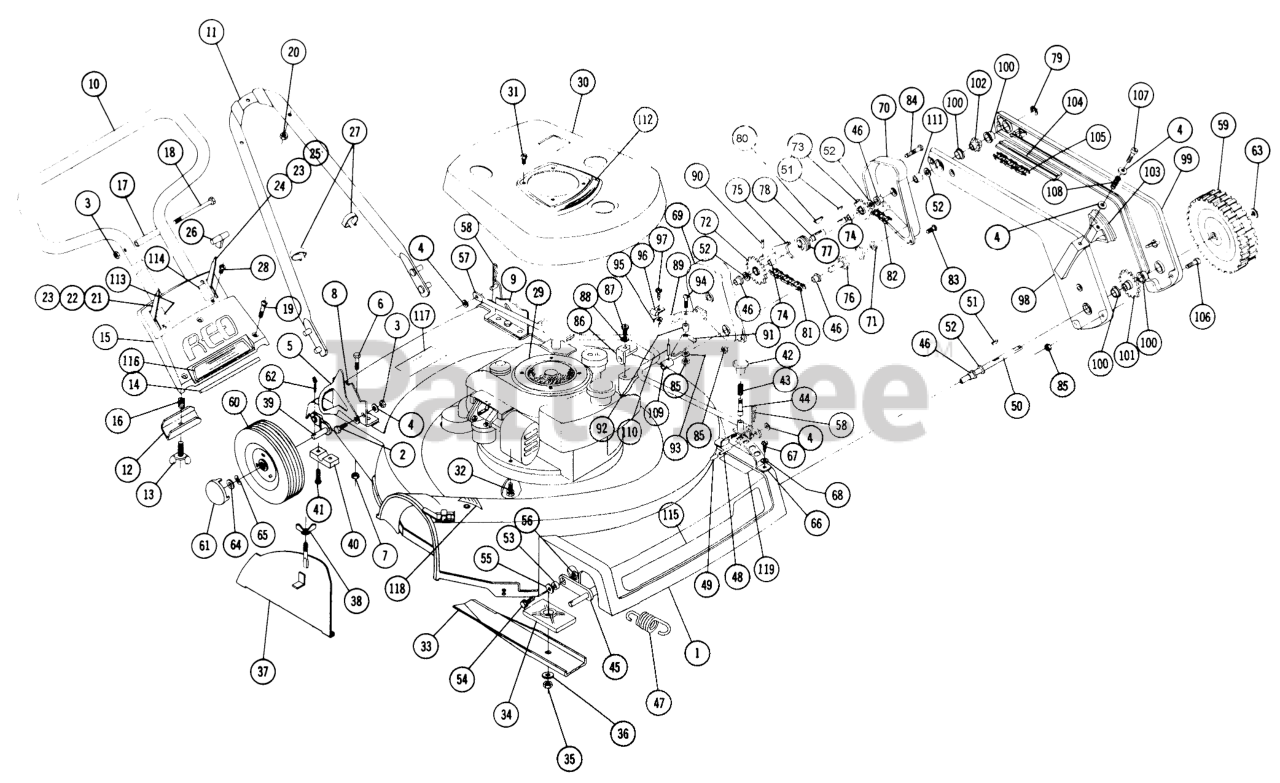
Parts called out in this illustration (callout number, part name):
1	Ass-y Deck
2	Bolt-1/4-20 x 5/8
3	Nut-Nylok
4	Washer
5	Latch-Handle Mounting
6	Bolt 5/16-18 x
7	Nut-Nylok
8	Bracket Handle R.H.
9	Bracket Handle L.H.
10	Handle-Upper
11	Handle-Lower
12	Channel-Clamp
13	Thumb Screw
14	Pin-Handle Pivot
15	Panel-Handle
16	SPRING-COMPRESSION
17	20210 '60&UP 21 SP
18	Bolt Hex 1/4-20 x 4 1/2
19	Screw Oval Head 1/4-20 x 1 1/2
20	Nut Hex 5/4-20 Nylok
21	Ass-y Throttle Control
22	31100 '60&UP 17 SNW
23	Ass-y. Cable
24	Ass-y. Clutch Control
25	Ass-y. Lever
26	Knob
27	Clip-Control
28	Screw #2 Phillips Sems #8-32 x 1/4
29	Engine
30	Shroud-Engine
31	Screw Sems 1/4-28 x 3/8
32	Screw Hex 5/16-18 x 1
33	Blade
34	Drive Blade
35	Nut Hex 5/8-18 Thin
36	Washer, 5/8
37	Ass-y Leaf Mulcher
38	Nut Wing 1/4-20
39	Ass-y Axle-Rear
40	Cap-Rear Axle Support
41	Screw Hex 1/4-20 x 7/8 Self Tap
42	KNOB
43	Spring
44	PLUNGER
45	Ass-y Height Adjustment Lever
46	BRONZE BUSHING
47	Spring
48	Roll Pin 1/8 Dia. x 1 1/2
49	Cap
50	Axle-Front
51	WOODRUFF KEY
52	Washer-Thrust
53	Spacer
54	Bolt 5/16-18 x 11/4
55	Washer
56	Nut 5/16-18
57	Rod-Wheel Adjustment Link
58	Hairpin
59	Wheel & Tire Assembly
60	Wheel & Tire Assembly
61	Cap-Hub
62	Hairpin
63	Washer
64	Washer
65	Washer
66	Quadrant-Height Adjustor
68	Lockwasher #10 External
69	Case-Trans. R.H.
70	Case-Trans. L.H.
71	BUSHING
72	Ass-y. Sprocket & Hub
73	Ass-y. Sprocket & Hub
74	Bearing
75	Ass-y Yoke & Shaft
76	Ass-y. Input Shaft & Sprocket
77	Collar-Shift
78	Shaft Output
79	E Ring
80	HI PRO KEY
81	Chain-Roller
82	Chain-Roller
83	Bolt #10-32
84	Bolt #10-32 x 234 Round Head
85	HEX NUT 10-32 E.S.
86	Block-Transmission Block
87	Screw Hex 1/4-20 x 1 1/8 Type "F"
88	Lockwasher
89	Bracket Lever-Shift
90	Pin-Groove 7/64 x 1/2
91	Lever-Shift
92	Spacer Pivot
93	Washer-#10 SAE
94	Screw Round Head #10-32 x 7/8
95	Nut-Tinnerman
96	CLIP BOWDEN WIRE
97	Screw #10 x 1/2 Type A
98	Housing-Drive R.H.
99	Housing-Drive L.H.
100	BUSHING
101	Ass-y.-Sprocket & Hub
102	Ass-y.-Sprocket & Hub
103	Guide-Upper
104	Guide-Lower
105	Chain-Roller
106	Screw-Machine #10-32 x 1 1/4
107	Nut Hex #10-32 Elastic Stop
108	Spring
109	Coupling
110	Roll Pin
111	Spacer
112	Decal
113	Decal-Control Panel
114	Decal-Control Panel
115	MANUAL
116	Decal-Regal IV
117	4XC6485 GIS ROTARY
118	Decal-Caution
119	Decal-Height Indicator
